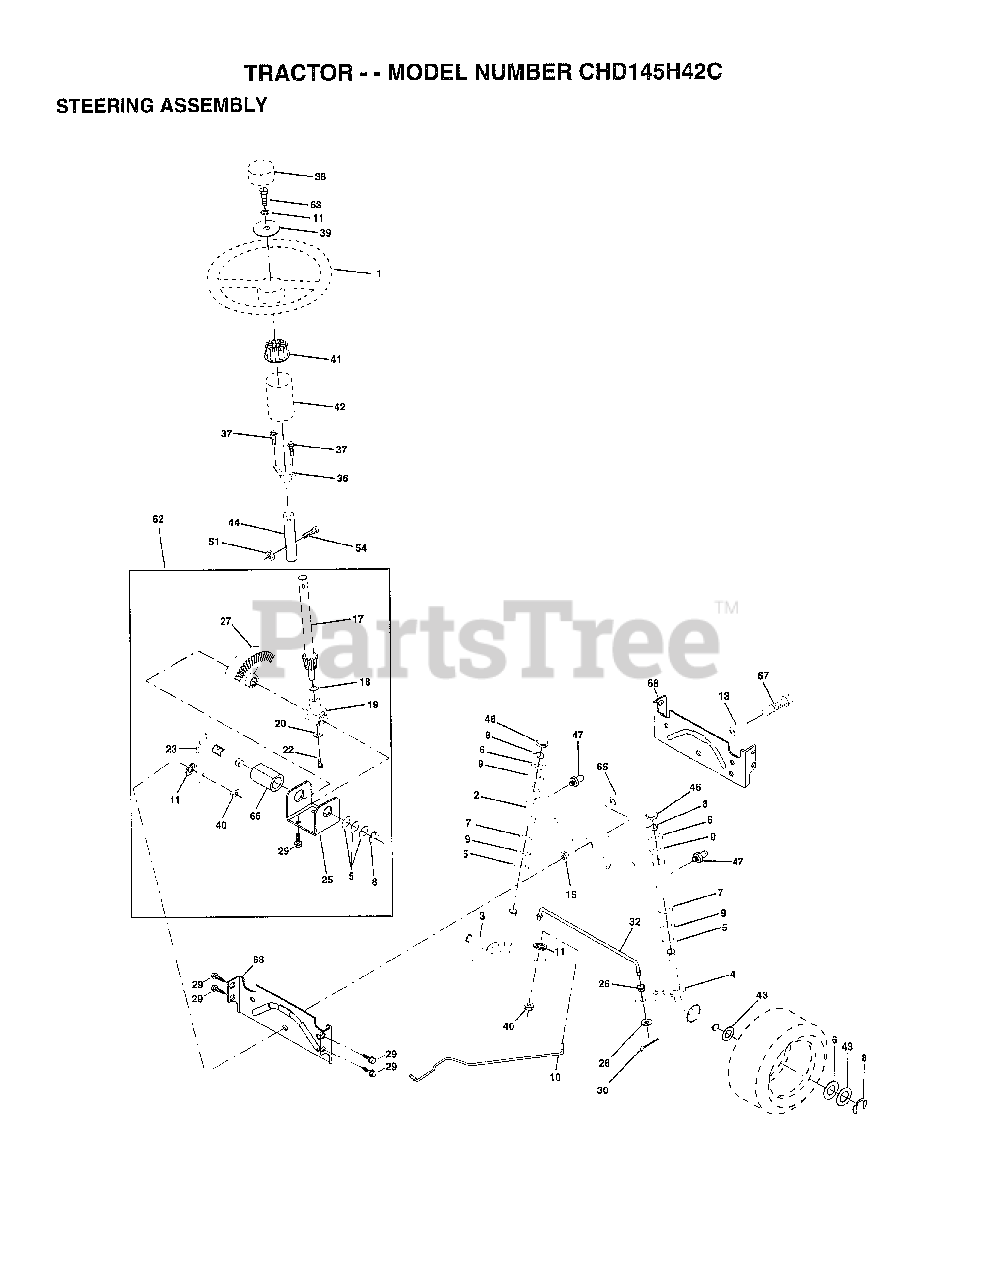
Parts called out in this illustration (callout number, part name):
1	WHEEL STR AYP BLK
2	AXLE ASM
3	SPINDLE.ASM.LH
4	"SPINDLE ASM,RH"
5	WASHER .T
6	WASHER
7	WASHER
8	RING
9	COL. SRTG. BEAR.
10	DRAGLINK-STAMPED
11	LOCKWASHER
13	BEARING AXLE
15	"NUT-LOC,FLANGE LT"
17	SHAFT ASM STEERIN
18	THRUST WASHER
19	SUPPORT.SHAFT
22	SCREW HEX SOC1/4-
25	BRKT-STEERING
26	BUSHING.DRAGLINK
27	GEAR SECTOR
28	WASHER
29	SCREW
30	COTTER PIN
32	TIE ROD
36	BUSHING.STEERING
37	"SCREW-TT,10-32 FL"
38	CAP STEER AYP
39	WASHER T
40	GRIPCO NUT
41	ADAPTER LT
42	BOOT.STEER.PL
44	EXT SHAFT STEERIN
46	CAP
47	ZERK M
51	NUT
54	BOLT
62	KIT STEERING ASM
63	BOLT
65	SPACER AXLE
66	"BEARING-ARM,PITMA"
67	BOLT
68	BRACE AXLE
